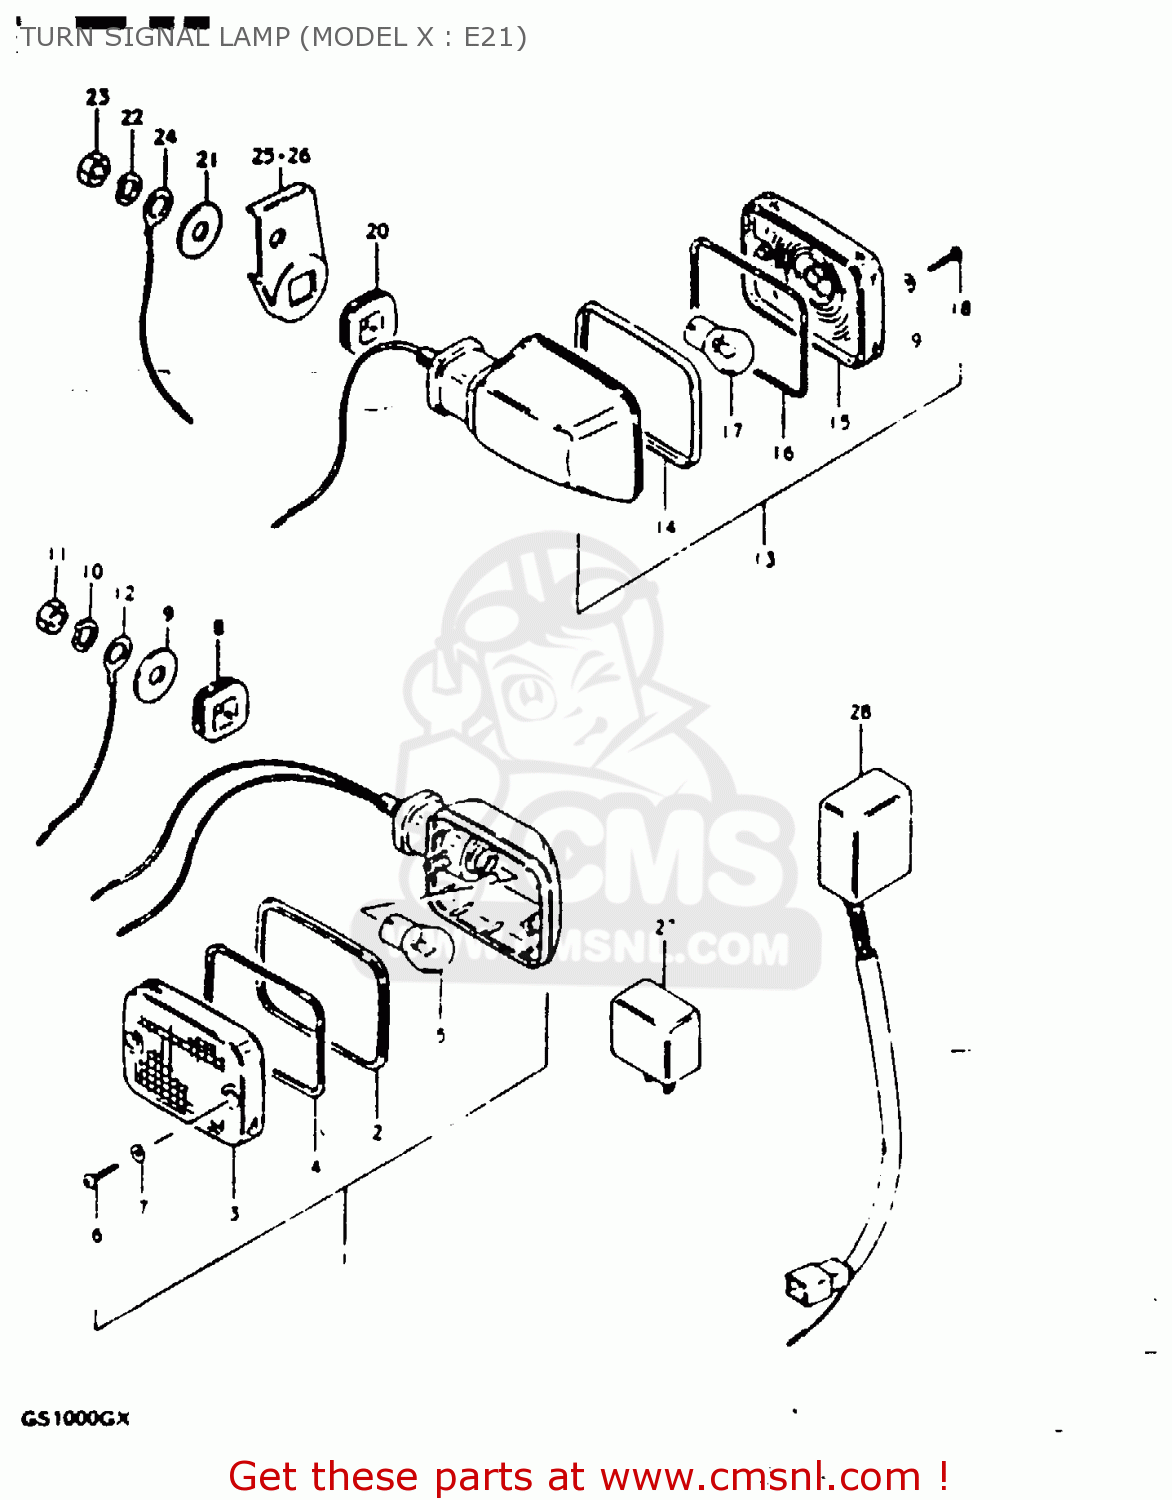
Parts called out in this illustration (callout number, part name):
1	LAMP, FRONT TURN SIGNAL
2	RIM
3	LENS
4	GASKET (NAS)
5	BULB 12V 21W
6	SCREW
7	GASKET (NAS)
8	CUSHION
9	WASHER (10.5X30X2.3)
10	LOCK WASHER
11	NUT
12	LEAD WIRE,EARTH
13	LAMP, REAR TURN SIGNAL
14	RIM
15	LENS
16	GASKET (NAS)
17	BULB 12V 21W
18	SCREW
19	GASKET (NAS)
20	CUSHION
21	WASHER (10.5X30X2.3)
22	LOCK WASHER
23	NUT
24	LEAD WIRE,EARTH
25	BRACKET,RR TURNSIGNAL LAMP,R
26	BRACKET,RR TURNSIGNAL LAMP,L
27	RELAY ASSY,TURNSIGNAL
28	UNIT,TURN SIGNAL CONTROL
